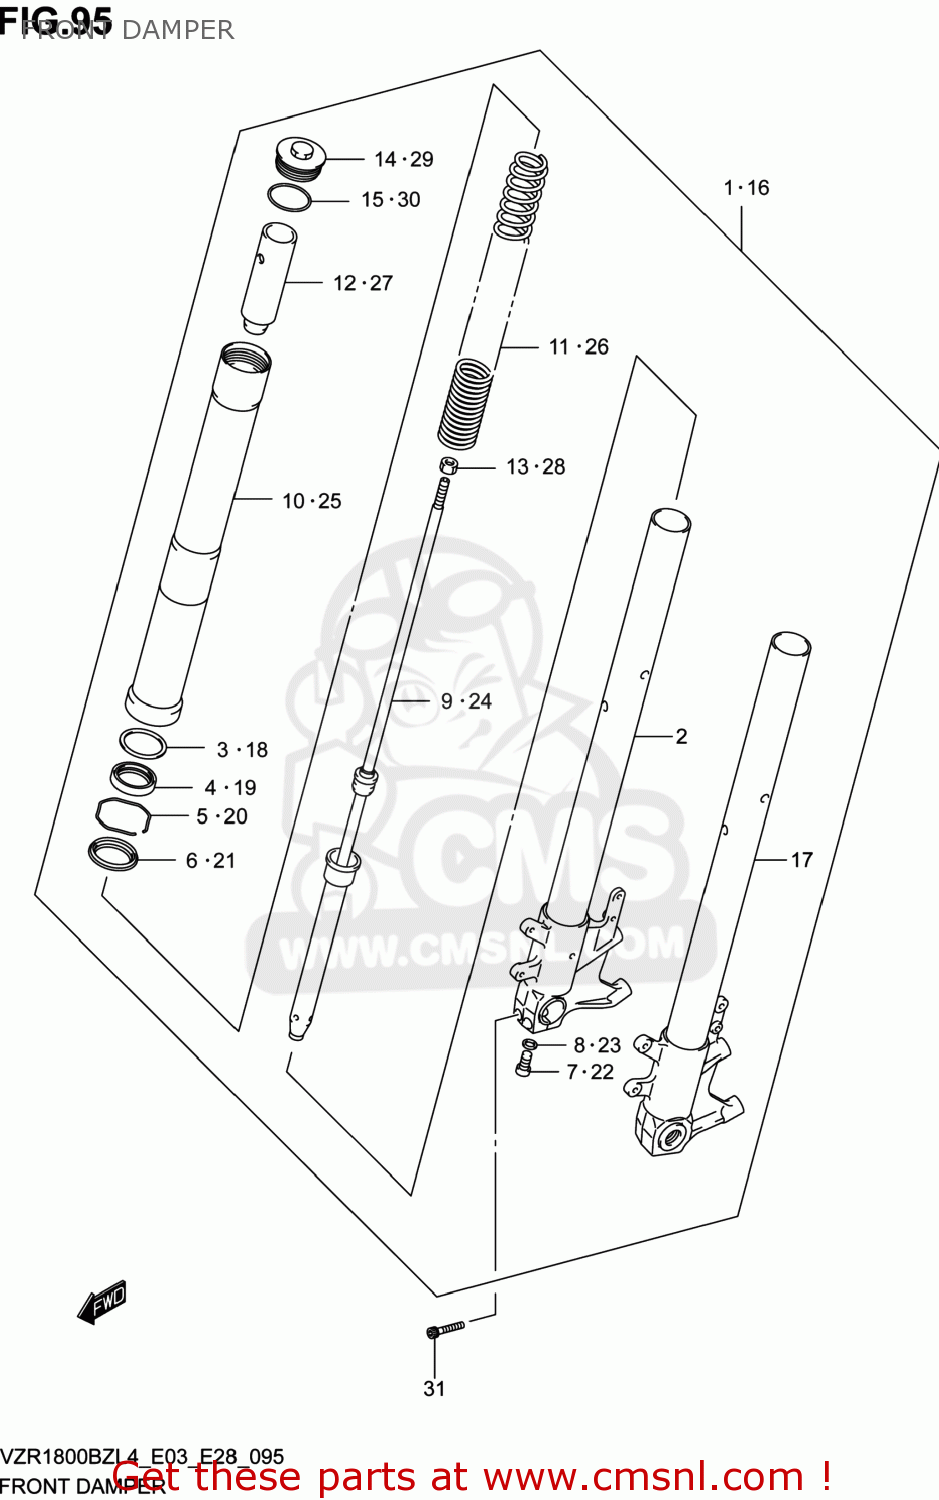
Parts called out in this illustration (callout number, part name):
1	DAMPER ASSY,FR FORK,R
2	TUBE,INNER,R
3	WASHER
4	SEAL,OIL
5	RING,STOPPER
6	SEAL,DUST
7	BOLT
8	GASKET (NAS)
9	CYLINDER
10	TUBE,OUTER
11	SPRING,FR
12	SPACER,SPRING
13	NUT,ROD
14	CAP
15	O RING
16	DAMPER ASSY,FR FORK,L
17	TUBE,INNER,L
18	WASHER
19	SEAL,OIL
20	RING,STOPPER
21	SEAL,DUST
22	BOLT
23	GASKET (NAS)
24	CYLINDER
25	TUBE,OUTER
26	SPRING,FR
27	SPACER,SPRING
28	NUT,ROD
29	CAP
30	O RING
31	BOLT,HOLDER HANDLE UPR
